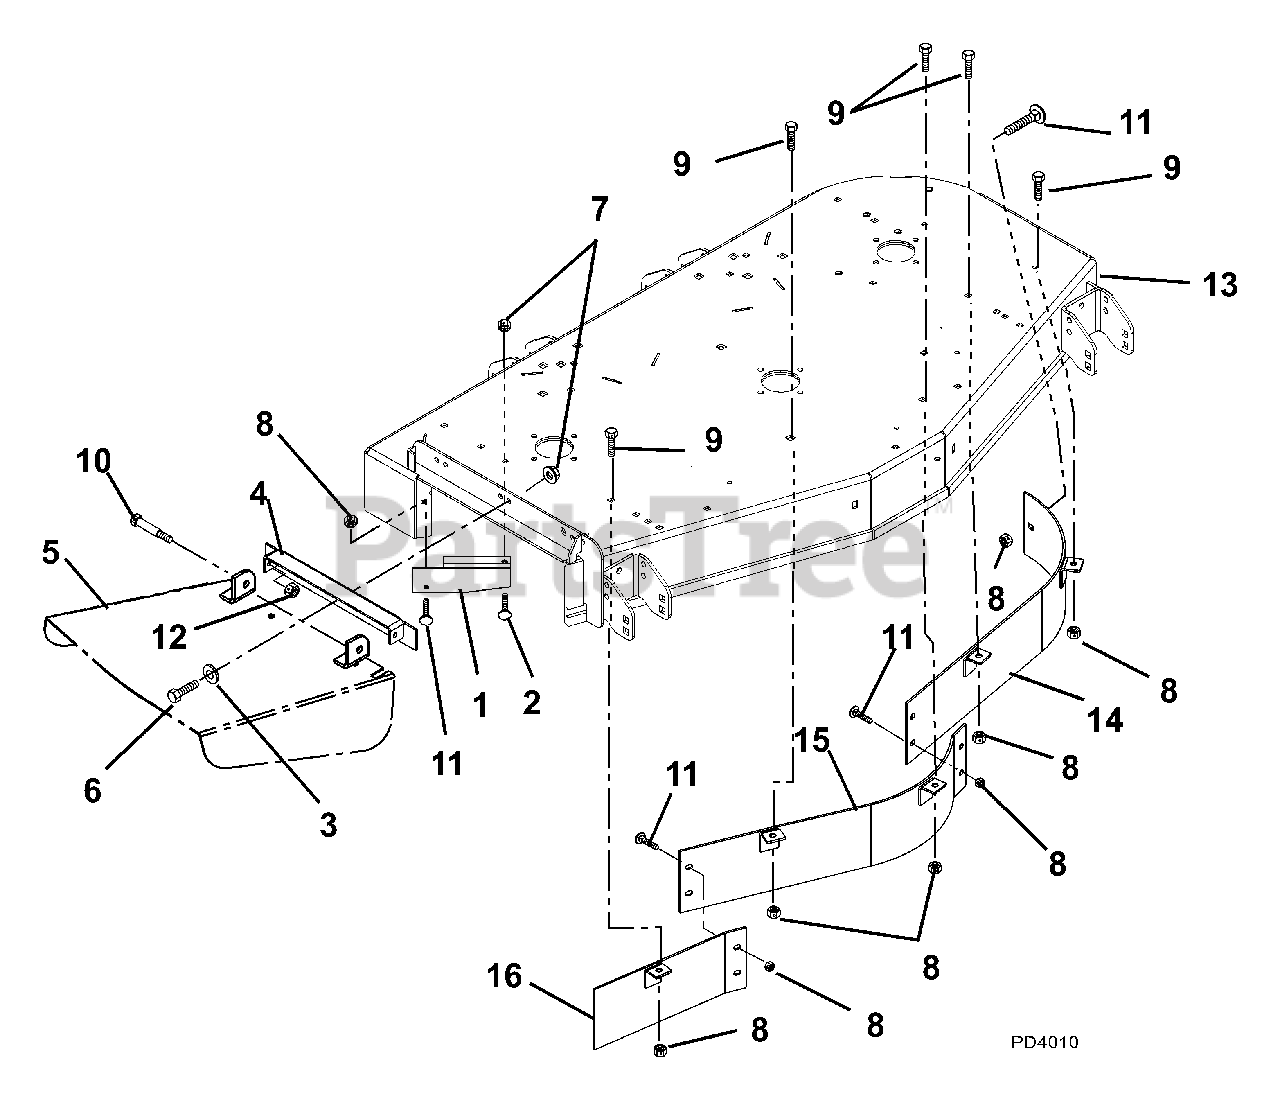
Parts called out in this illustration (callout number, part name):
1	Deflector, 44"
2	Bolt, Round Head Square Neck .38-16 x 1.00 Grade 5
3	Washer, Flat Steel .38 x .875 x .083
4	Weldment Discharge Chute Bracket
5	Chute, Discharge
6	Bolt, Hex .38-16 x 1.00 Grade 5
7	Nut, Nyloc Flange 3/8-16
8	Nut, Nyloc Flange 5/16-18
9	Bolt, Hex .31-18 x .75 Grade 5
10	Bolt, Shoulder .38-16 x .50 Socket Head
11	Bolt, Round Head Square Neck .31-18 x .75 Grade 5
12	Nut, Locking Center .38-16
13	Weldment, 44" Mower Deck Float
14	Baffle, Left Front - 44"
15	Weldment, Baffle Center Front - 44"
16	Weldment, Baffle Right Front - 44"
